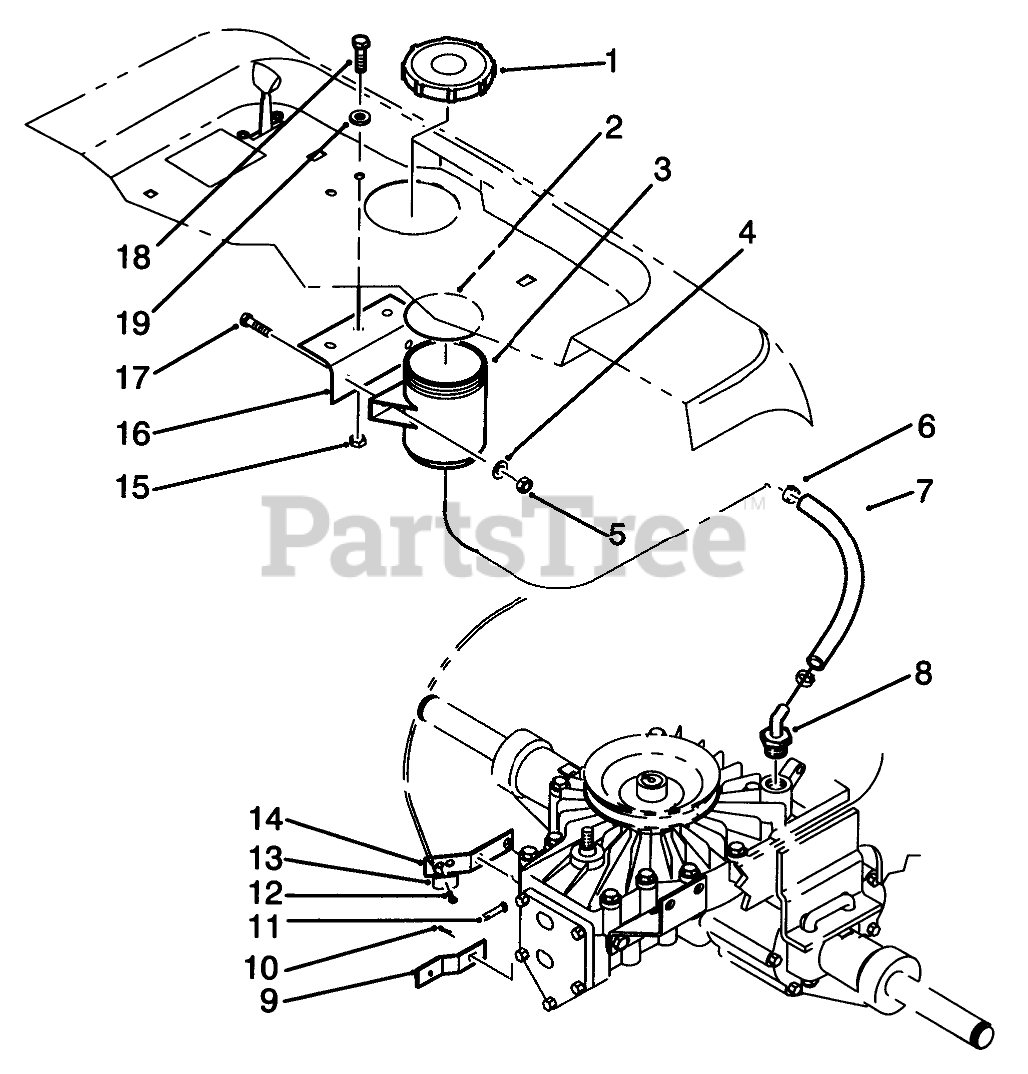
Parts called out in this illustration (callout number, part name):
1	ASS'Y-RESERVOIR
2	COVER GASKET
3	RESERVOIR
4	WASHER-FLAT
5	NUT-LOCK, NI
6	CLAMP .875
7	HOSE-7"
8	HOSE BARB
9	Plate
10	Cotter Pin
12	Screw
13	CLAMP THROTTLE
14	PLATE-MTG
15	NUT-LOCK, NI
16	BRACKET R
17	SCREW-HH
18	SCREW-HH
19	WASHER-PLAIN
